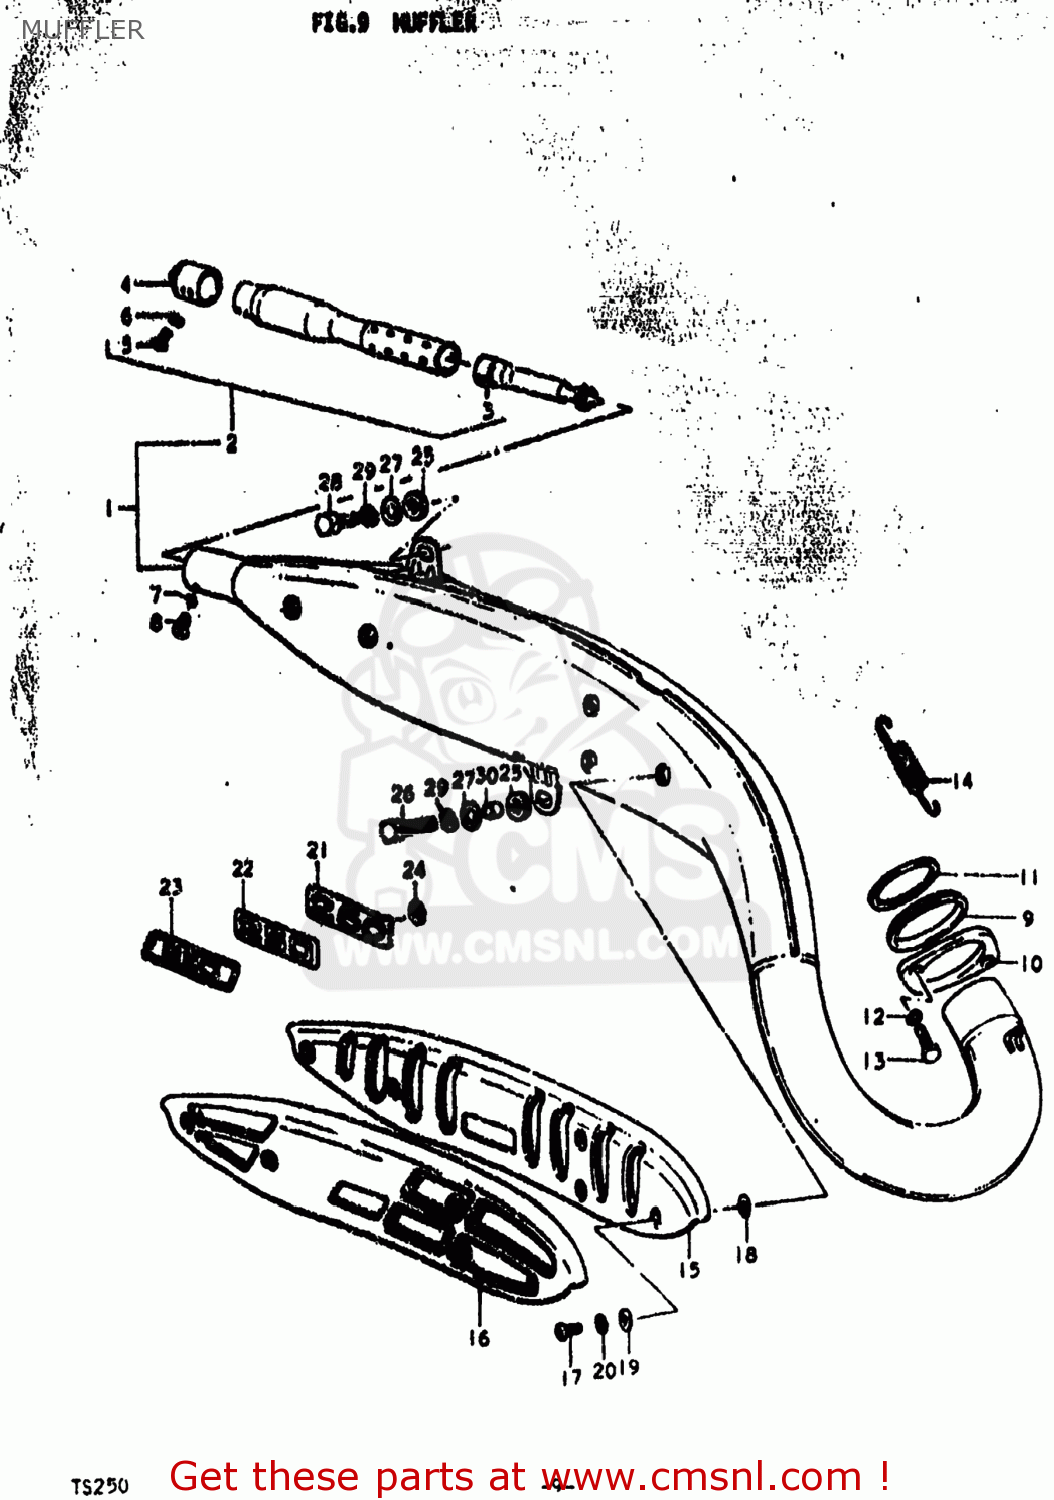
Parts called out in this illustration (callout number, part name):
1	MUFFLER ASSEMBLY
2	ARRESTER,SPARK
3	TUBE,CLEAN OUT
4	CUTTER,SPARK ARRESTER
5	SCREW
6	LOCK WASHER
7	LOCK WASHER
8	SCREW
9	GASKET,EXHAUST PIPE (NAS)
10	CLAMP,EXHAUST PIPE
11	GASKET,EXHAUST PIPE
12	LOCK WASHER
13	BOLT
14	SPRING
15	COVER,MUFFLER
16	COVER,MUFFLER
17	SCREW
18	GASKET 6.2X12X1.5 (MCA)
19	WASHER
20	LOCK WASHER
21	EMBLEM,MUFFLER COVER
22	EMBLEM,MUFFLER COVER
23	EMBLEM,MUFFLER COVER
24	NUT
25	CUSHION
26	BOLT
27	WASHER
28	BOLT
29	LOCK WASHER
30	SPACER
